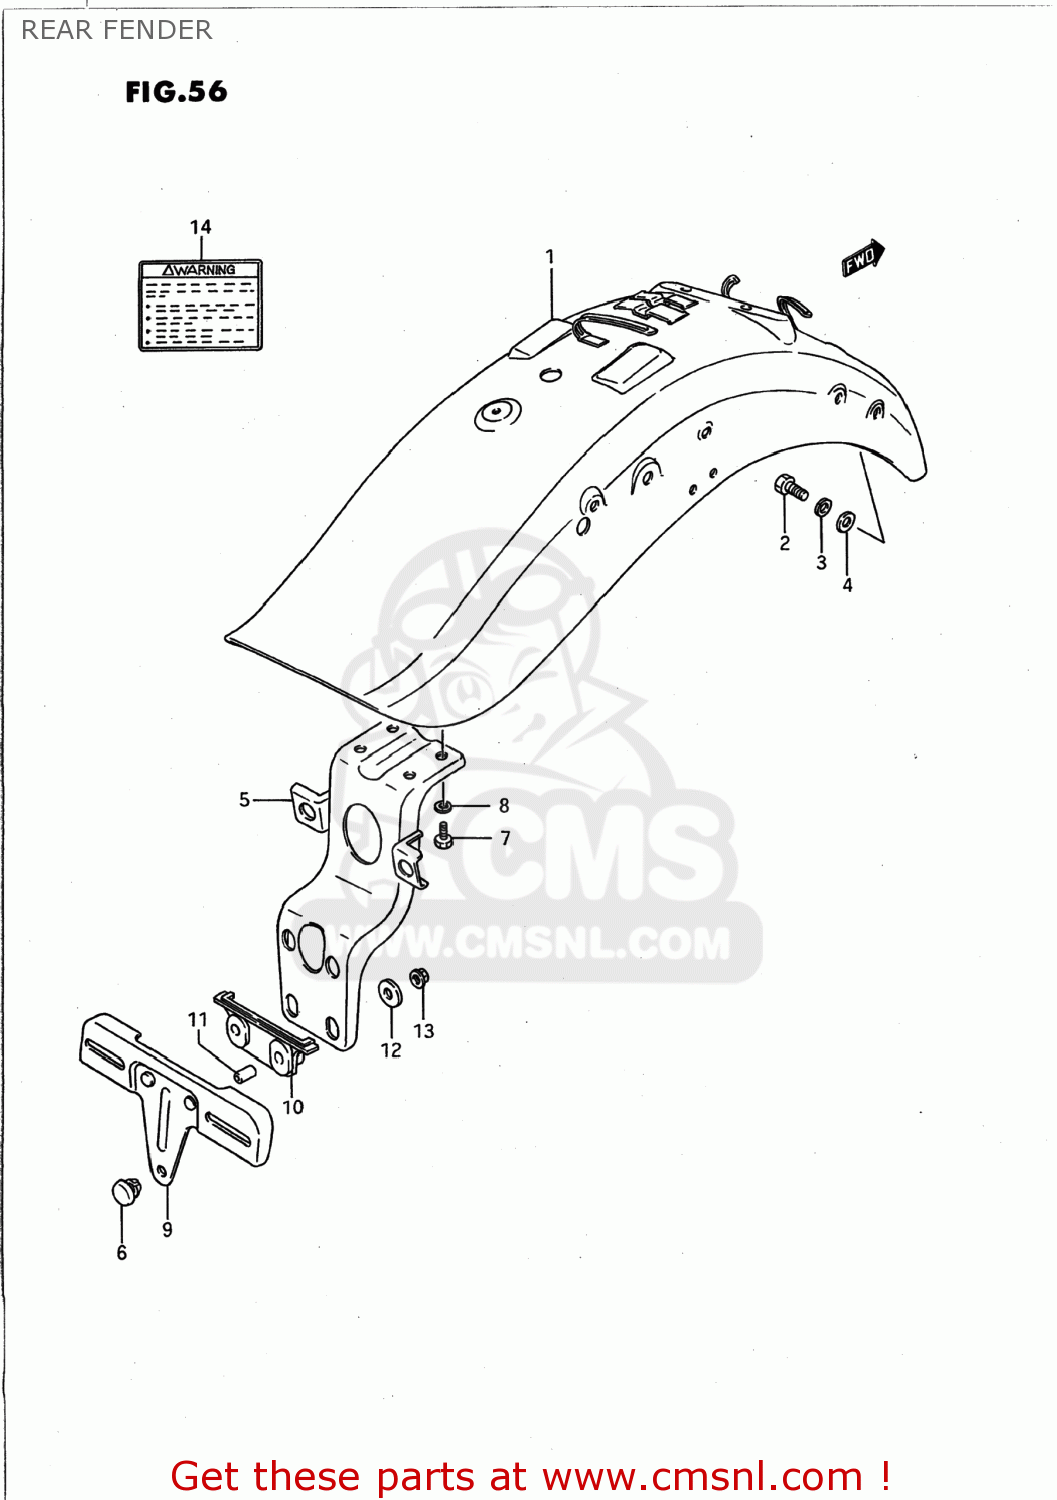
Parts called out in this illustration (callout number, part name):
1	FENDER COMP,REAR
2	BOLT
3	WASHER,LOCK,8.
4	WASHER 8MM
5	BRACKET,RR COMBINATION LAMP
6	CUSHION
7	BOLT
8	WASHER,LOCK
9	PLATE,REAR LICENSE
10	CUSHION,RR LICENSE PLATE
11	SPACER (5.5X7.5X14.3)
12	WASHER(5.5X20X1.2)
13	NUT
14	LABEL
15	LABEL (TIRE AIR PRESSURE)
16	LABEL (VACUUM HOSE ROUTING)
17	OWNER`S MANUAL VS 1400GL
